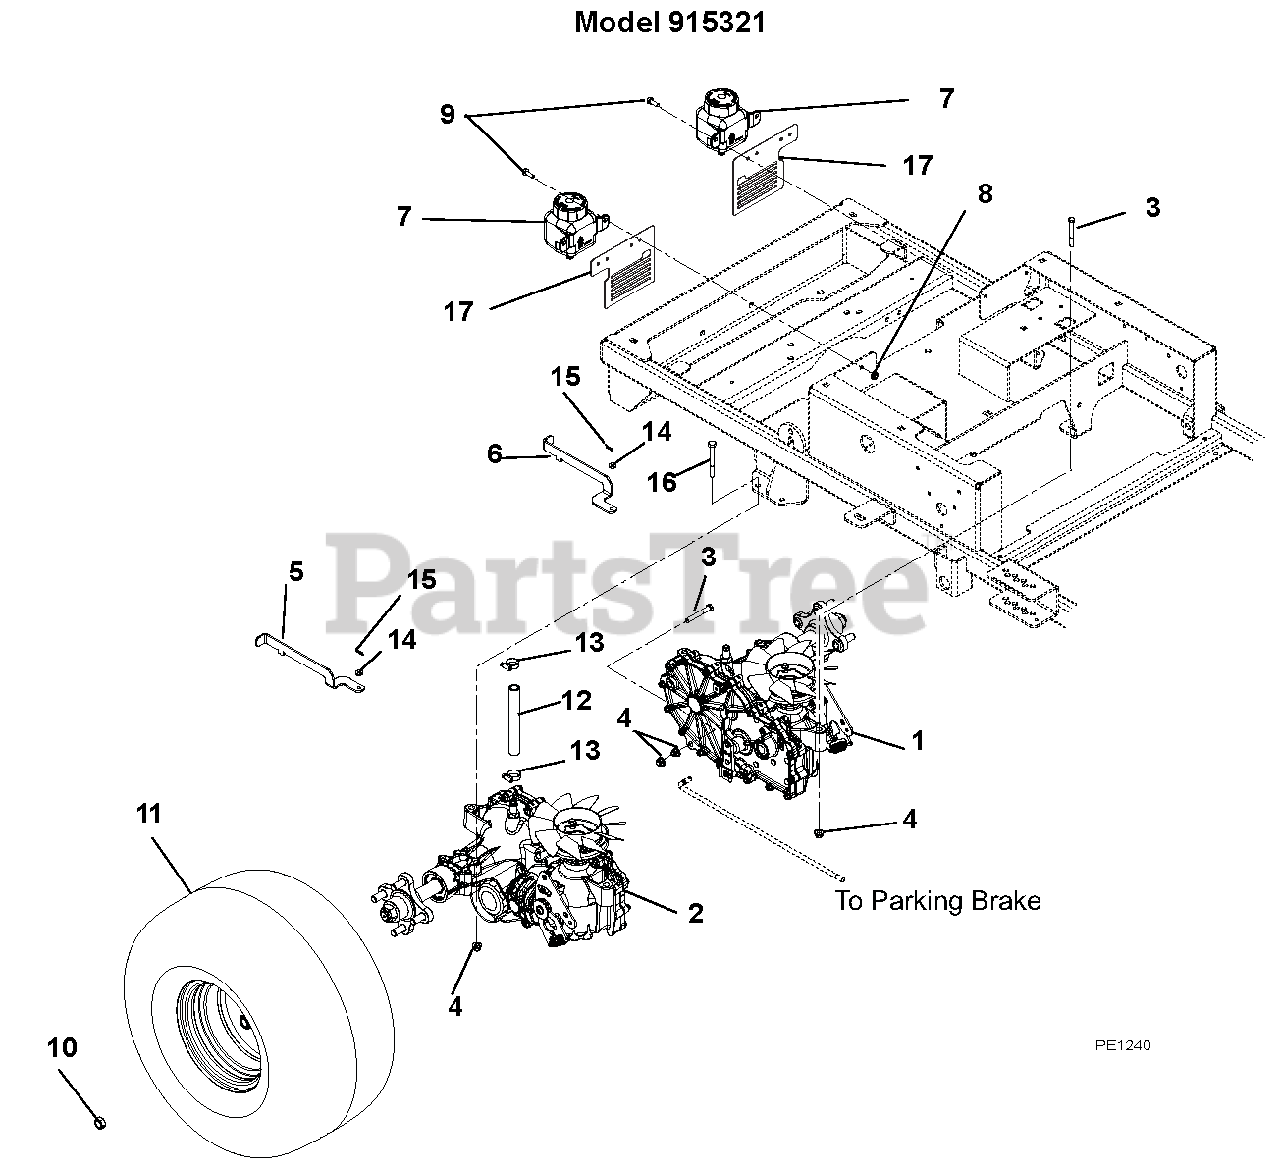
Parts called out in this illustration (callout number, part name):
1	TRANSAXLE, ZT2800 LH
2	TRANSAXLE, ZT2800 RH
3	@BLT-HEX .31-18X2.25 GR5 YWZC
4	@NUT-LK-NYL-FLG .31-18 YWZC
5	DUMP VALVE, RH
6	DUMP VALVE, LH
7	TANK, EXPANSION
8	@NUT-LK-TOP-FLG .25-20 YWZC
9	@BLT-HEX .25-20X.75 GR5 YWZC
10	WHEEL NUT .500-20 YZ
11	TIRE/WHEEL ASM, 20X8.0-8 (SQ)
12	HOSE, OIL RESERVOIR
13	CLAMP,.88 DIA. HOSE
14	WSHR-FL-STL .265X.50X.087YWZC
15	PIN-HAIR INT .06X.18X.77
16	@BLT-HEX .31-18X2.75 GR5 YWZC
17	BRKT, REAR FAN GUARD
